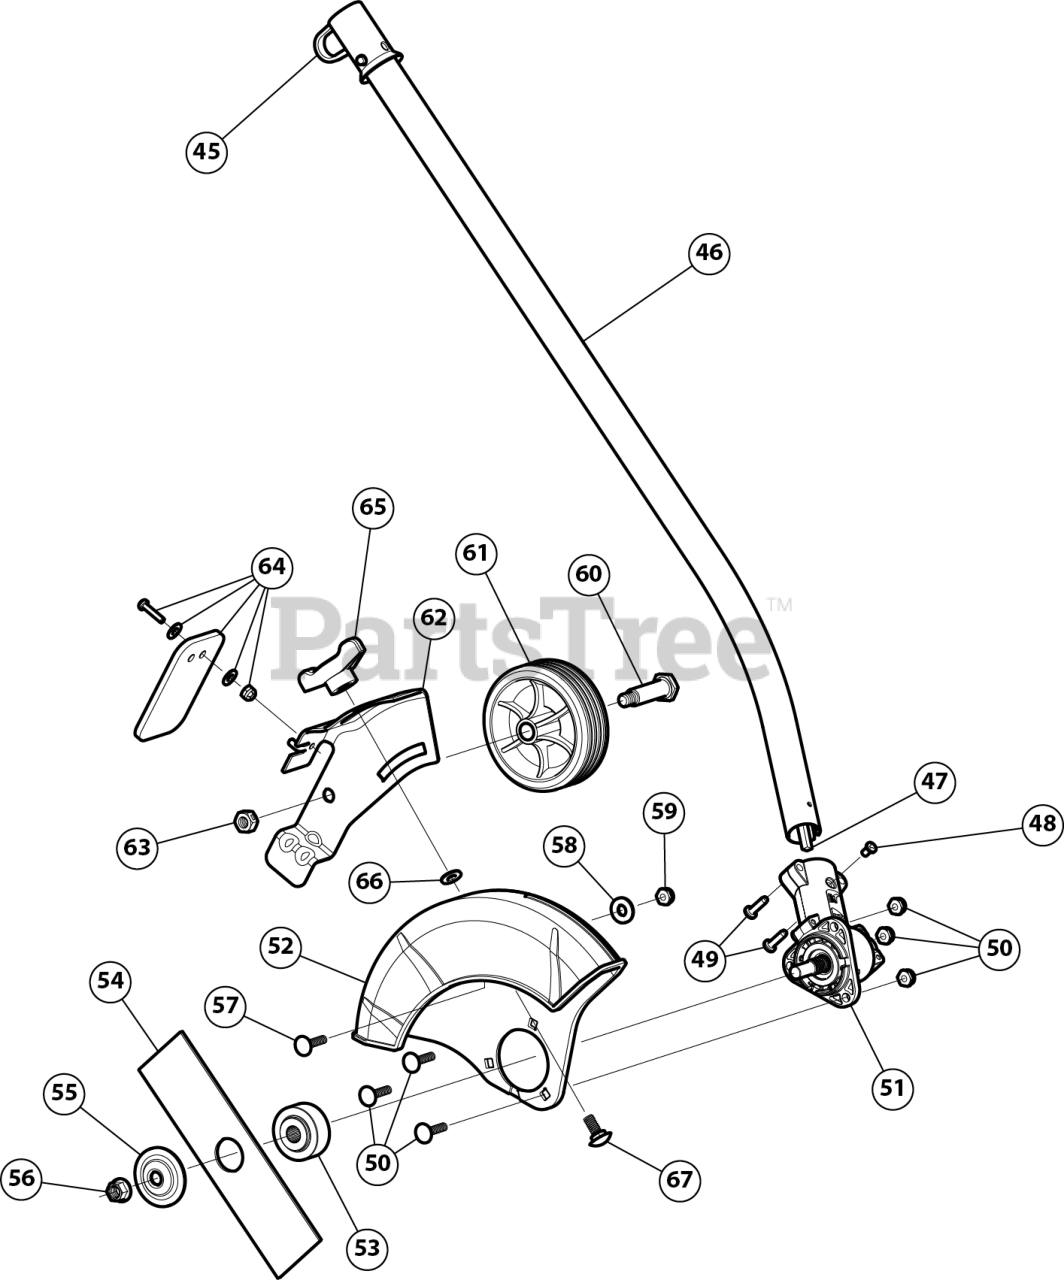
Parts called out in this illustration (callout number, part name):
45	PLUG CAP
46	BOOM ASSEMBLY LE
47	LOWER DRIVE SHAFT
48	SCREW, 8-32 x .312 P
49	SCREW #10-24X11/16 T-25
50	HDWR ASM:GUARD MT
51	GRBX ASSEMBLY
54	8" EDGER BLADE
55	WASHER-BLADE CLAMP BRUSH CUT
56	BLADE LOCK NUT
57	CARRIAGE BOLT 1/4-20 x 1
58	FLAT WASHER
59	NUT 1/4-20 NYLOC
60	SHOULDER SCREW 0.498x1.494 3/8-16
61	WHEEL 3.75" (WHITE)
62	BRACKET GUARD
63	LOCK NUT 3/8-16
64	DEFLECTOR W/HDW
65	WING KNOB 5/16-18
66	WASHER .406X1.0X.095
67	CARRIAGE BOLT 5/16-18 x .75
